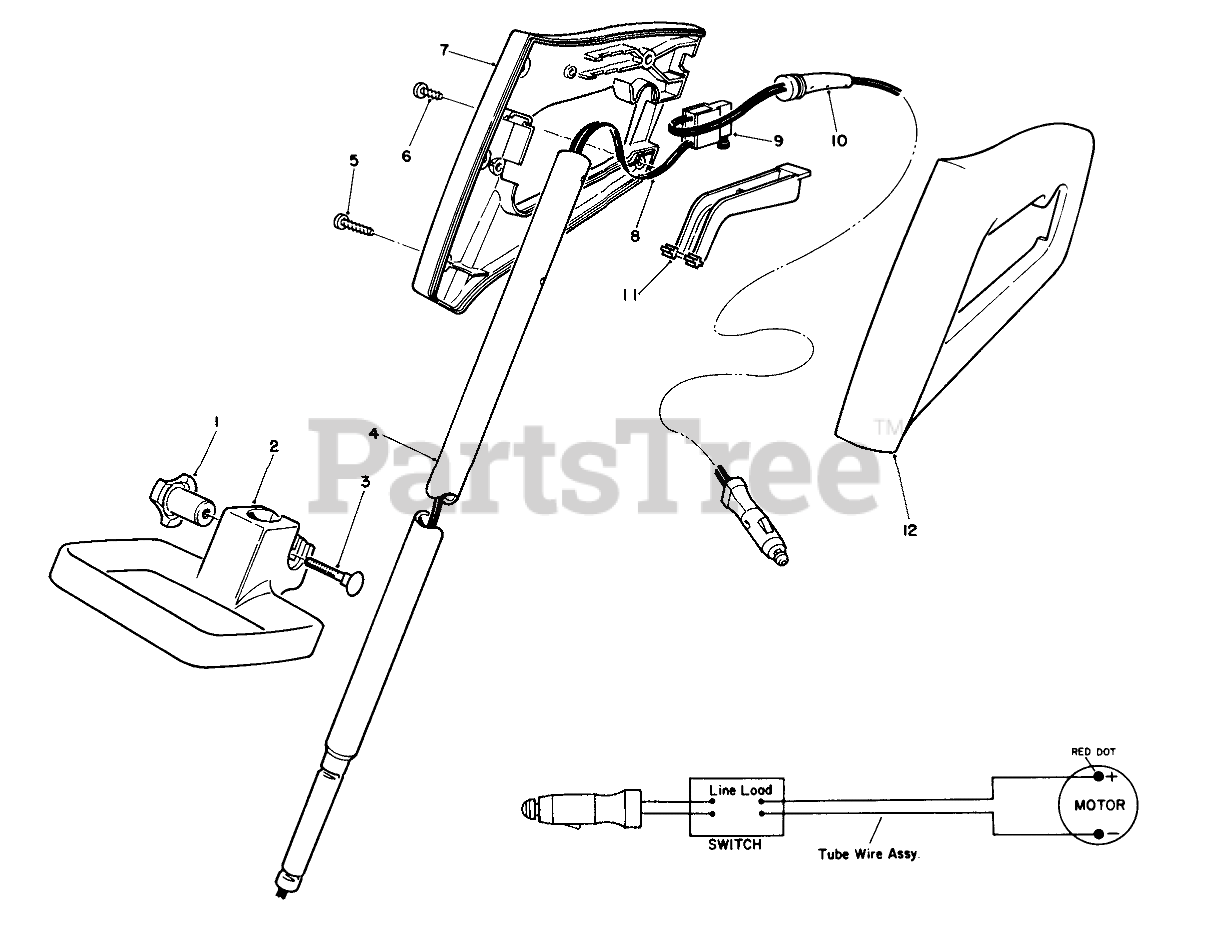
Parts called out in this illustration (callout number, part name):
1	Knob
2	Handle-Adjust
3	BOLT-CARR
4	TUBE-SINGLE
5	Screw
6	SCREW-PPH
7	HANDLE GRIP, RH
8	WIRE ASSEMBLY-TUBE
9	SWITCH
11	TRIMMER-SWITCH BAR
12	HANDLE GRIP, LH
